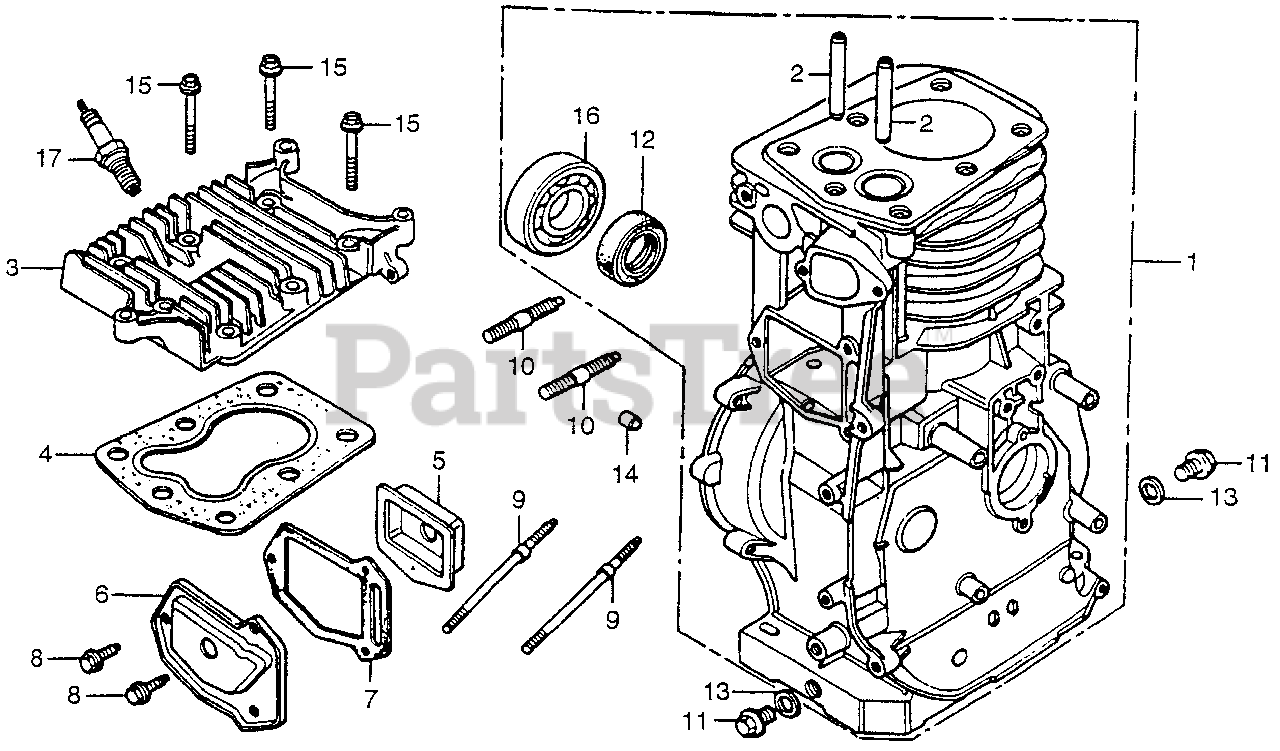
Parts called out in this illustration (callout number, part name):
1	CYLINDER ASSY. (NOT AVAILABLE)
2	GUIDE, VALVE (OS)
3	CYLINDER HEAD
4	GASKET, CYLINDER HEAD
5	CASE, BREATHER
6	COVER, TAPPET ROOM
7	GASKET, TAPPET COVER
8	BOLT, FLANGE (6X12) (CT200)
9	BOLT, STUD (6X96)
10	BOLT, STUD (8X35)
11	BOLT, DRAIN PLUG
12	OIL SEAL (25X41X6)
13	WASHER, DRAIN PLUG (12MM)
14	PIN A, DOWEL (8X14)
15	BOLT, FLANGE (8X45)
16	BEARING, RADIAL BALL (6205)
17	SPARK PLUG (BR6HS) (NGK)
